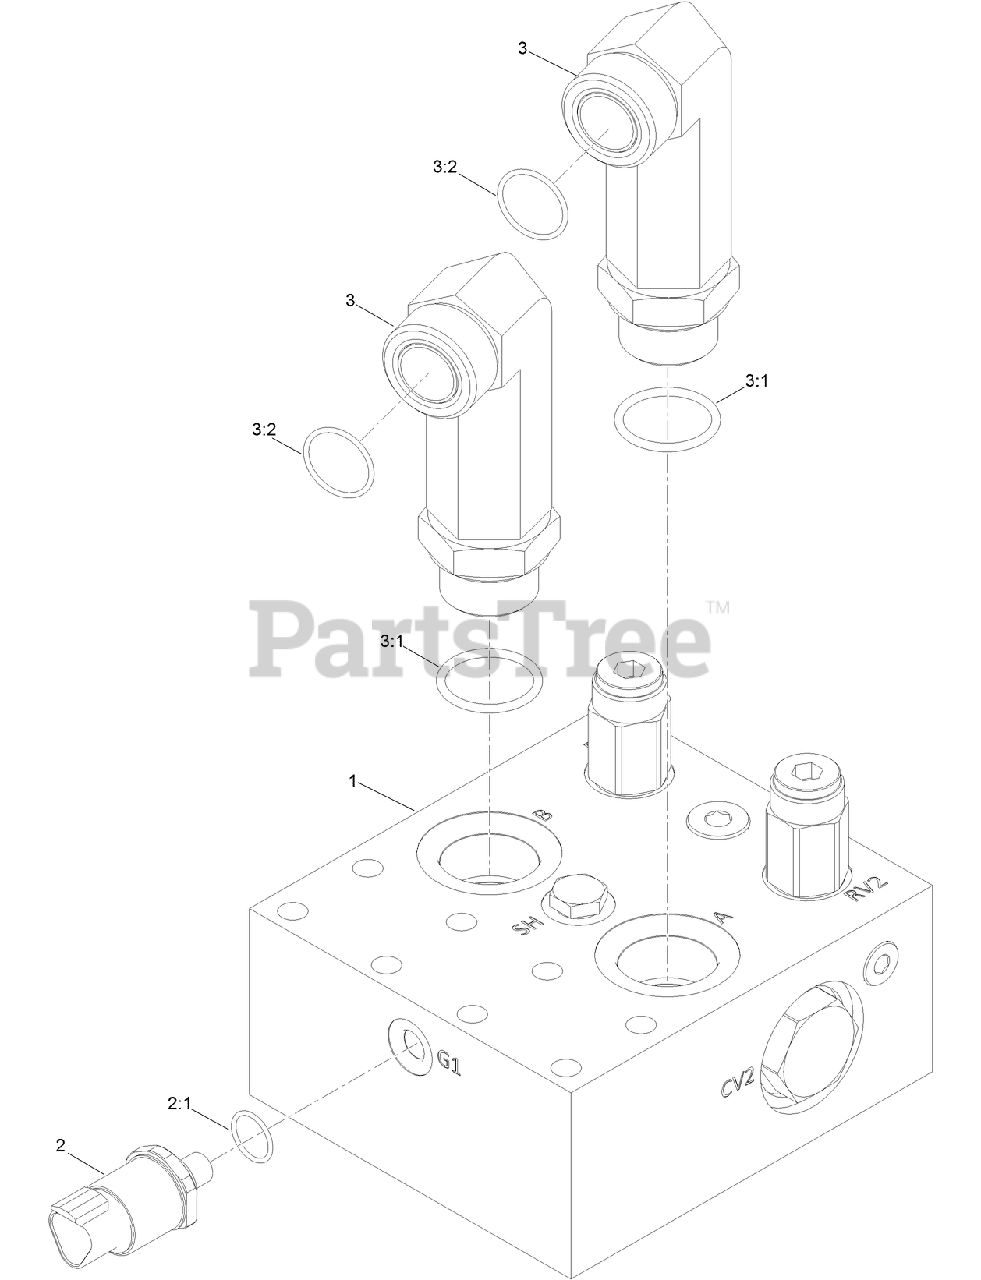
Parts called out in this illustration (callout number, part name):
1	ROTARY RELIEF MANIFOLD ASM
2	TRANSDUCER
2:1	O-RING
3	FITTING-ELBOW, 90 LONG
3:1	O-RING
3:2	O-RING
